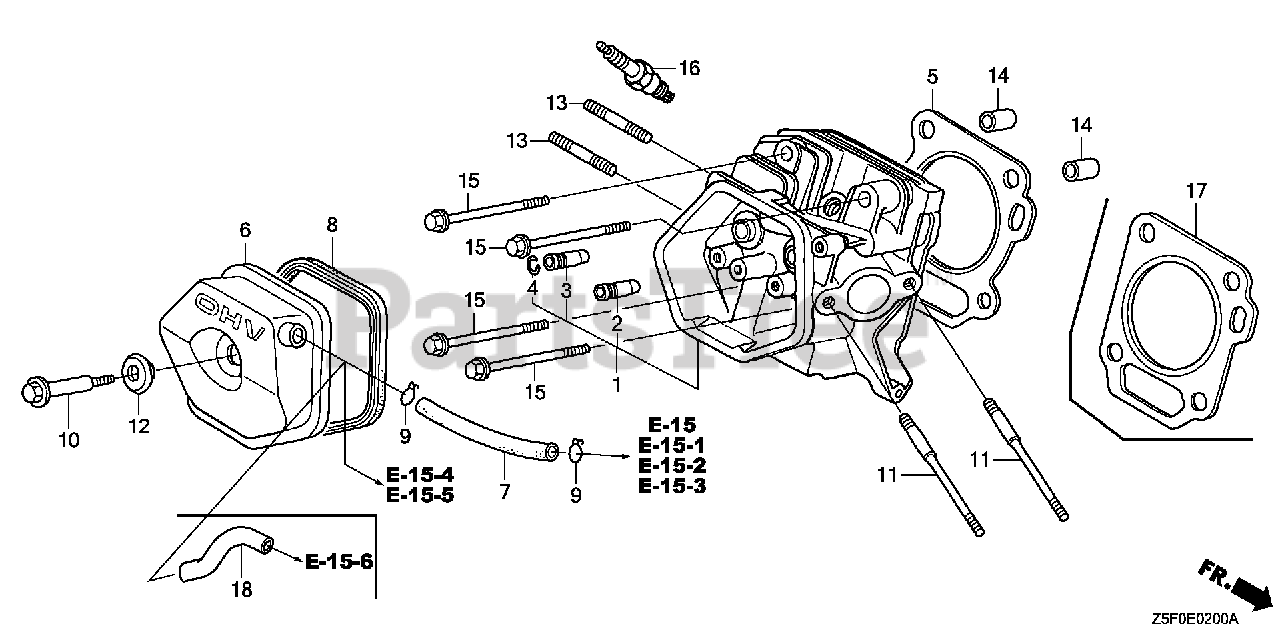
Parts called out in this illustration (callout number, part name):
1	CYLINDER HEAD
2	GUIDE, VALVE (OVER SIZE)
3	GUIDE, EX. VALVE (OVER SIZE)
4	CLIP, VALVE GUIDE
5	GASKET, CYLINDER HEAD
6	COVER, HEAD
7	BULK HOSE, VACUUM (11X1000) (11X100)
8	GASKET, HEAD COVER
10	BOLT, HEAD COVER
11	BOLT, STUD (8X123)
12	WASHER, HEAD COVER
13	BOLT, STUD (8X32)
14	PIN, DOWEL (12X20)
15	BOLT, FLANGE (10X80)
16	SPARK PLUG (BPR5ES) (NGK)
16	SPARK PLUG (W16EPR-U) (DENSO)
16	SPARK PLUG (BPR6ES) (NGK)
16	SPARK PLUG (W20EPR-U) (DENSO)
